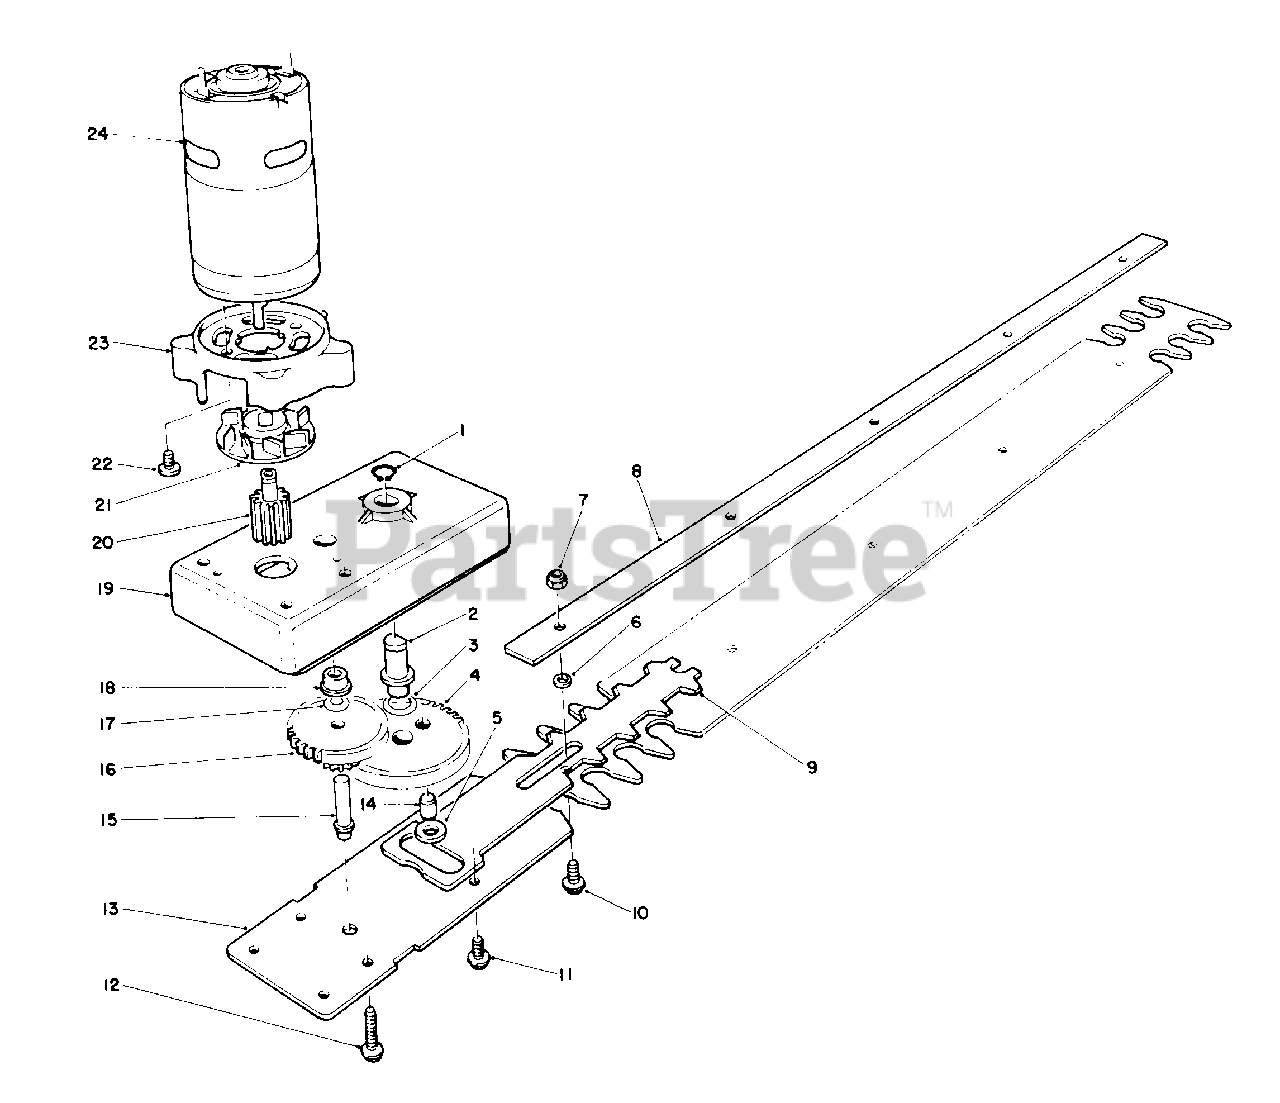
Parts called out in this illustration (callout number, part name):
1	Ring-Retaining
2	Shaft-Driver
3	Washer-Wave
4	Gear-Drive (Incl. Ref. #14)
5	Bushing-Gear, Drive
6	Bushing-Blade
7	Nut-Lock
8	Retainer-Blade
9	Blade-Cutting
10	Screw-Hex Washer Hd.
11	Screw-Hex Washer Hd.
12	Screw-Hex Washer Hd.
13	Blade-Bottom
14	Pin-Drive
15	Shaft-Idler
16	Gear-Idler
17	Washer-Wave
18	Bearing-Idler
19	Housing-Gear Assembly (Incl Ref. 2 & 18)
20	Gear-Motor
21	Fan-Motor
22	Screw-Phil. Pan Hd.
23	Support-Motor
24	Motor Assembly (Incl. Ref. #20-23)
